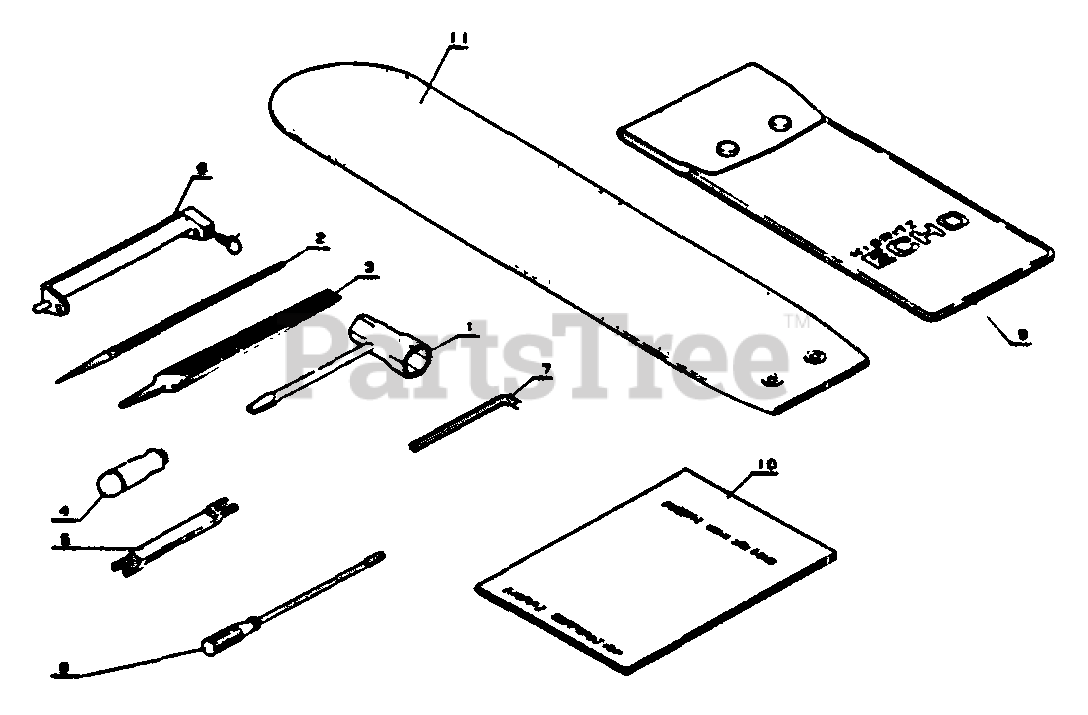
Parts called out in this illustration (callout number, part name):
1	T-WRENCH 13×19×180
2	ROUND FILE
3	FLAT FILE
4	FILE GRIP
5	GAUGE, DEPTH
6	FILE HOLDER
7	WRENCH, ALLEN 4 MM
8	SCREWDRIVER, SLOTTED
9	BAG, TOOL
11	COVER, CHAIN
